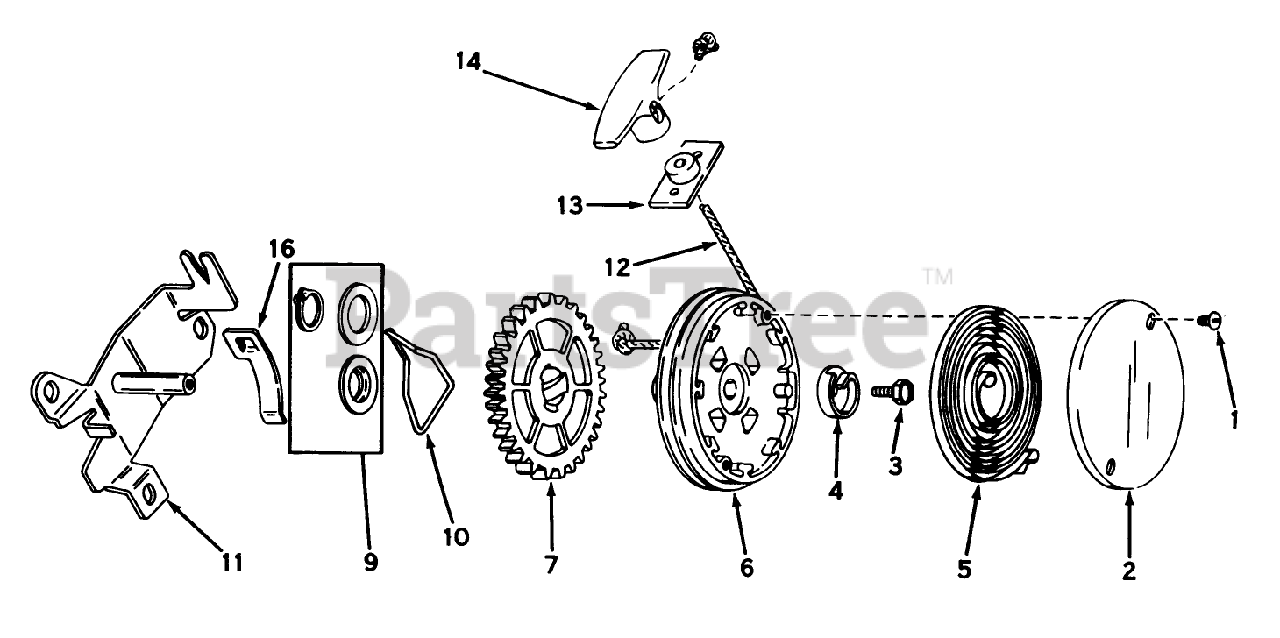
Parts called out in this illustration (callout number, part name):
2	Cover, Spring
3	Screw, Hex Washer Head
4	Hub Spring
5	Spring, Rewind
6	Pulley Assy. (Incl. Ref. #9)
9	Kit, Thrust Wash. & Snap Rg.
11	Bracket Assy. Mounting
12	Rope-Starter
13	Bracket Assy.
14	Handle-Starter
16	Clip Rope
